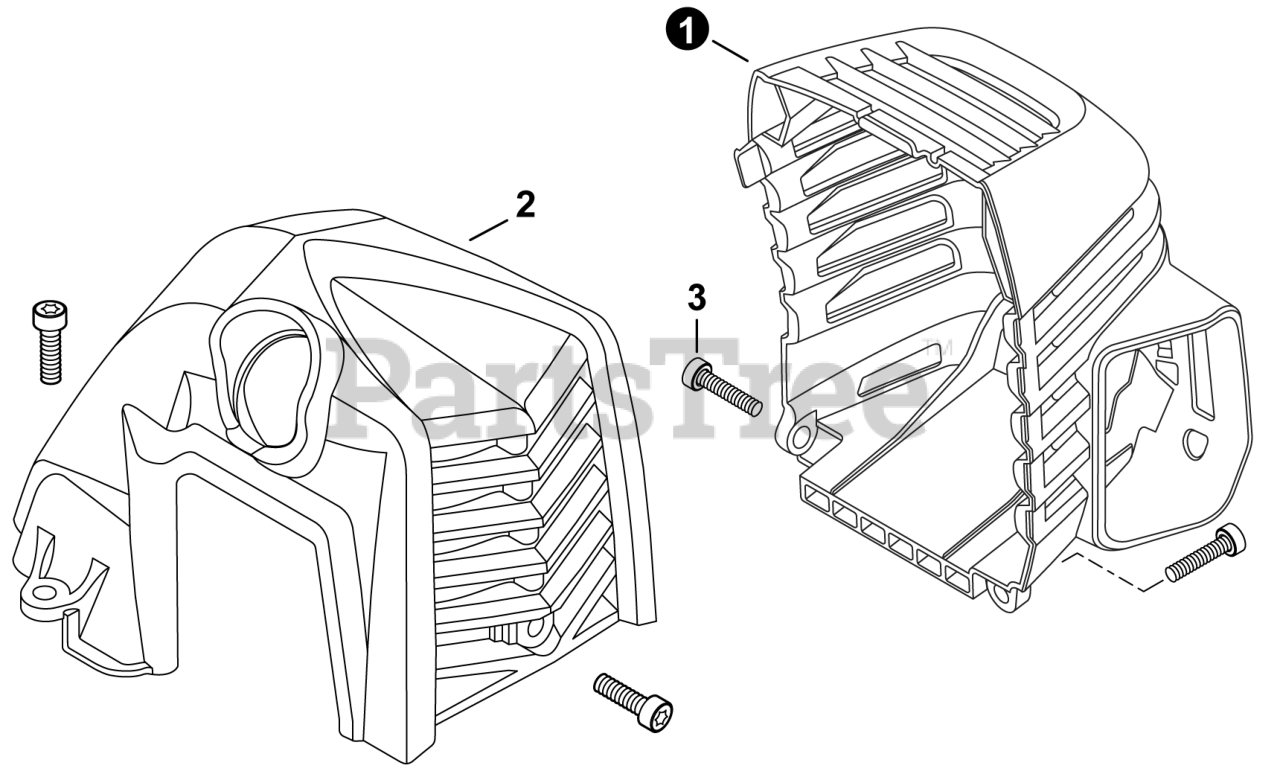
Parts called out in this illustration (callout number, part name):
1	COVER, MUFFLER
2	COVER, ENGINE
3	BOLT, TORX 5x12
